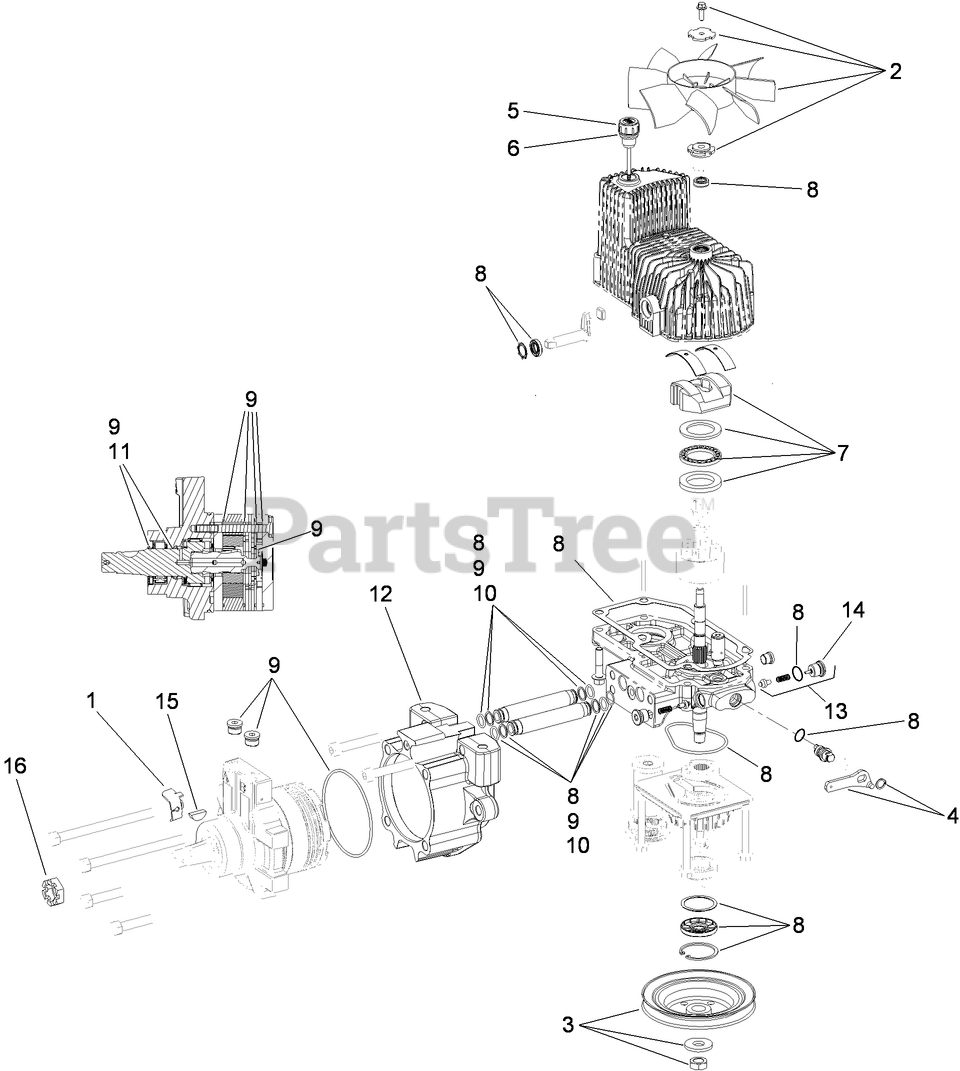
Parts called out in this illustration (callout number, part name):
1	BRACKET-ANCHOR, CABLE
2	FAN KIT
3	PULLEY KIT
4	HANDLE-BYPASS VALVE, HYDRO
5	DIPSTICK-HYDRO W/GASKET
6	GASKET-DIPSTICK, HYDRO
7	SWASH BLOCK KIT
8	PUMP SEAL KIT
9	MOTOR SEAL KIT
10	TUBE SEAL KIT
11	OUTPUT SHAFT SEAL KIT
12	CUP-NOSE
13	CHECK VALVE ASM
14	PLUG-CHECK (W/O-RING)
15	KEY-WOODRUFF
16	NUT-HH
